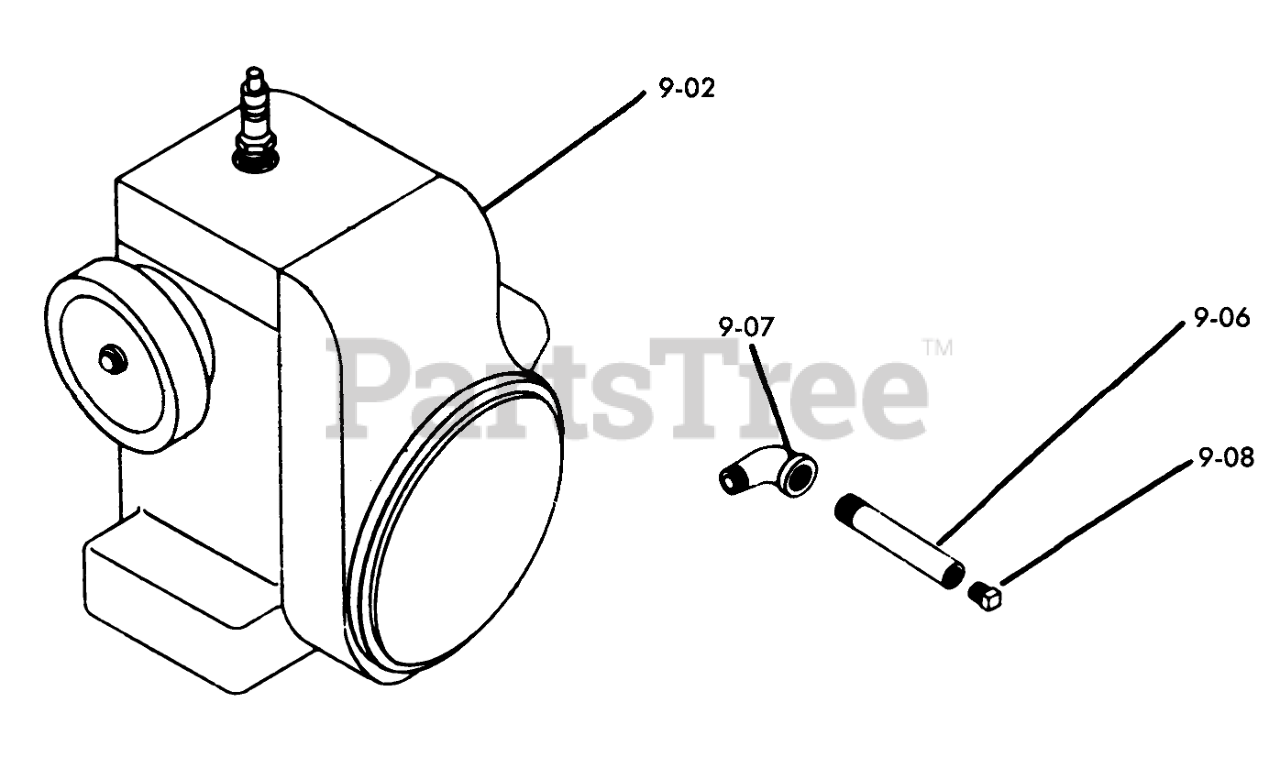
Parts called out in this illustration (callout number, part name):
9-02	Engine-12HP Kohler
9-02	Engine-16HP Kohler
9-06	Nipple 3/8 x 5
9-07	ELBOW-STREET
9-08	Cap
